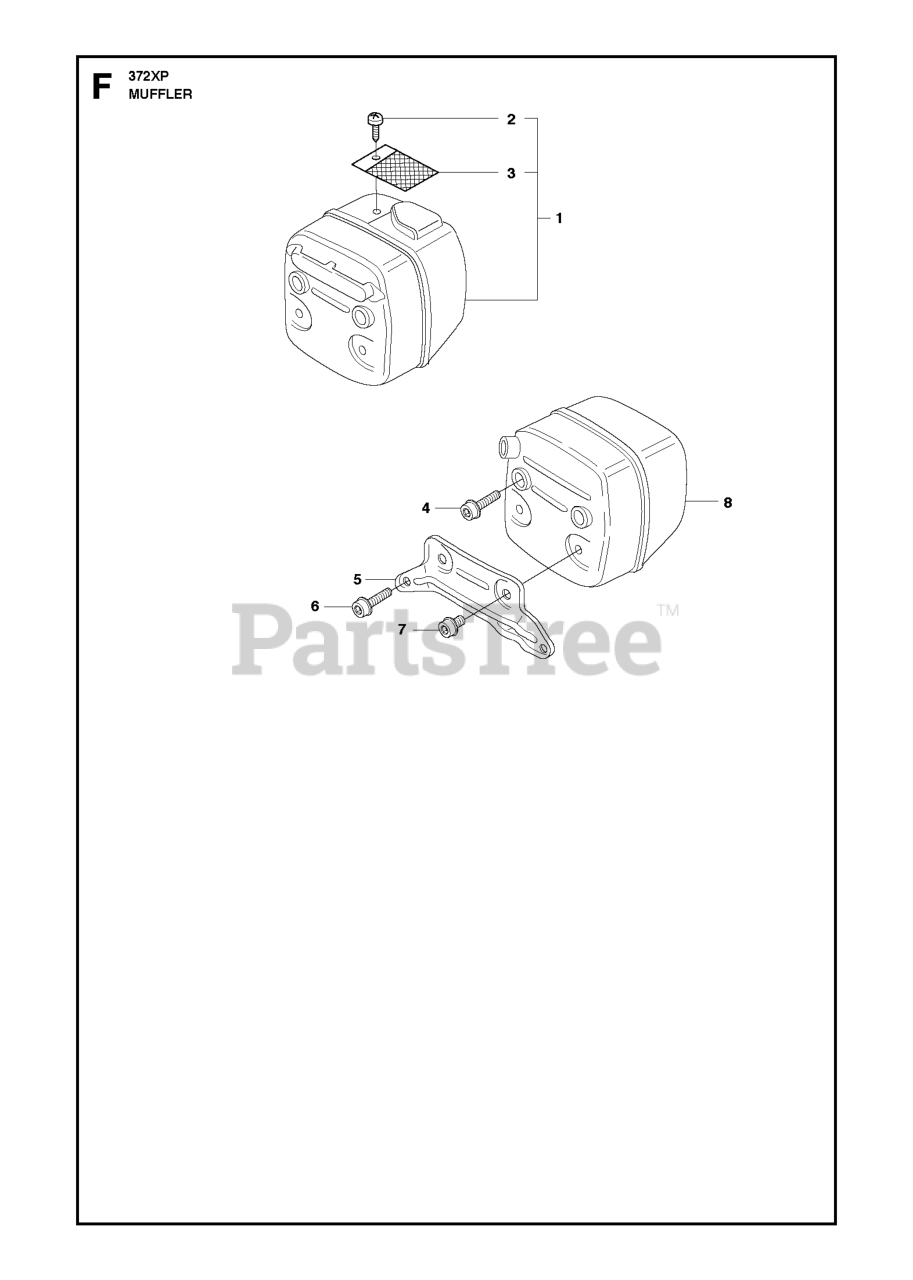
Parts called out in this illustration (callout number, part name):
1	MUFFLER
1	CARBURETOR
2	BODY-A-PUMP
4	SCREW ITXSCM M6X20 T27 12.9 T
5	NUT
6	SCREW IHSCFM
6	ADJUSTER
7	SCREW IHSCFM
8	MUFFLER ASSY
11	JET
